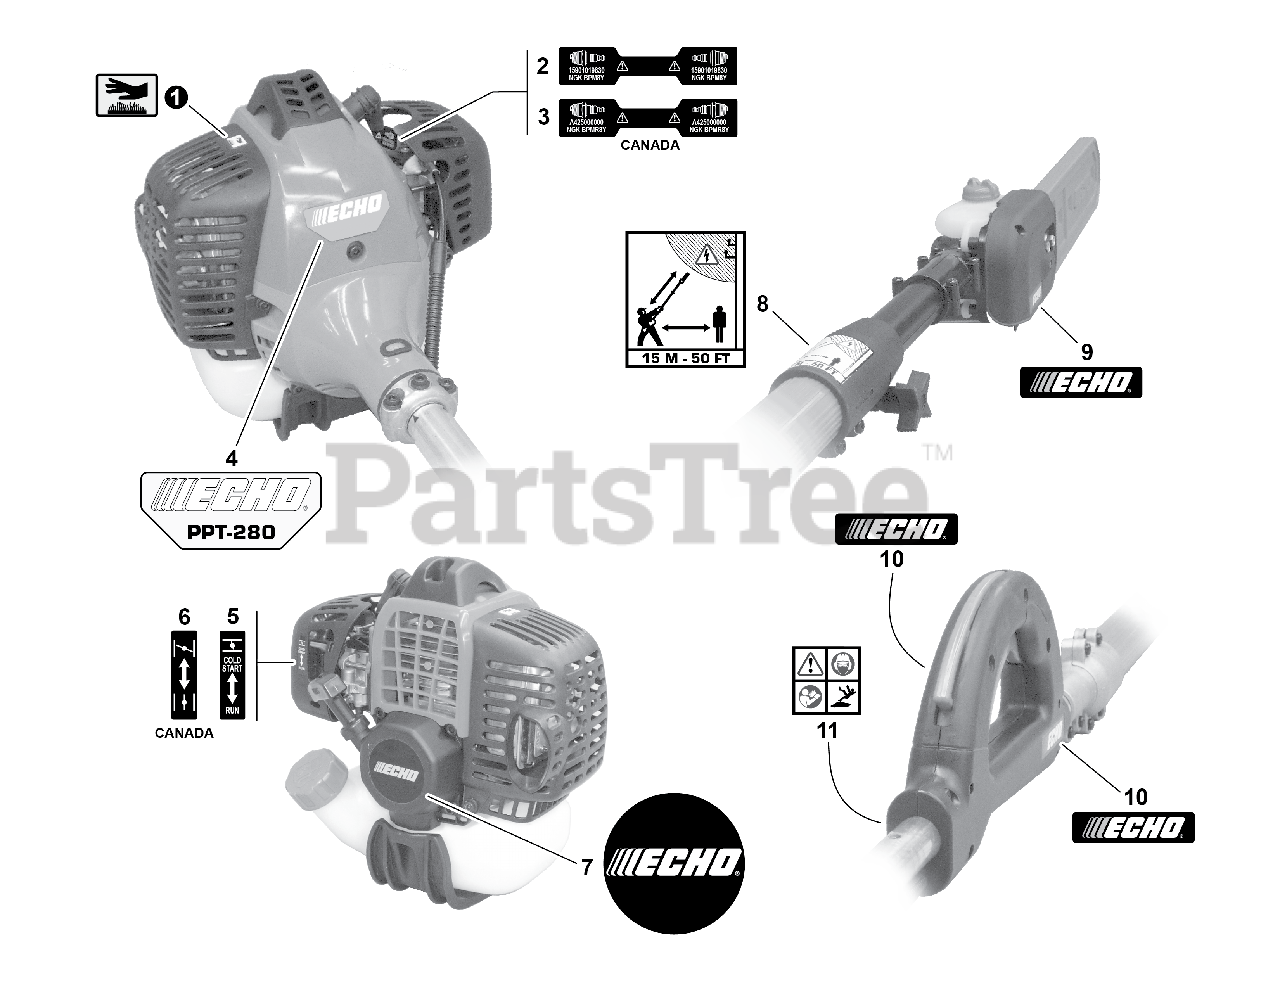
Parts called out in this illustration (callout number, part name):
1	LABEL - CAUTION -- HOT
2	LABEL - SPARK PLUG -- BPM8Y
3	LABEL - SPARK PLUG -- BPMR8Y
4	LABEL - MODEL -- PPT-280
5	LABEL - CHOKE
6	LABEL - CHOKE
7	LABEL - ECHO
8	LABEL - WARNING
9	LABEL - ECHO
10	LABEL - ECHO
11	LABEL - CAUTION
